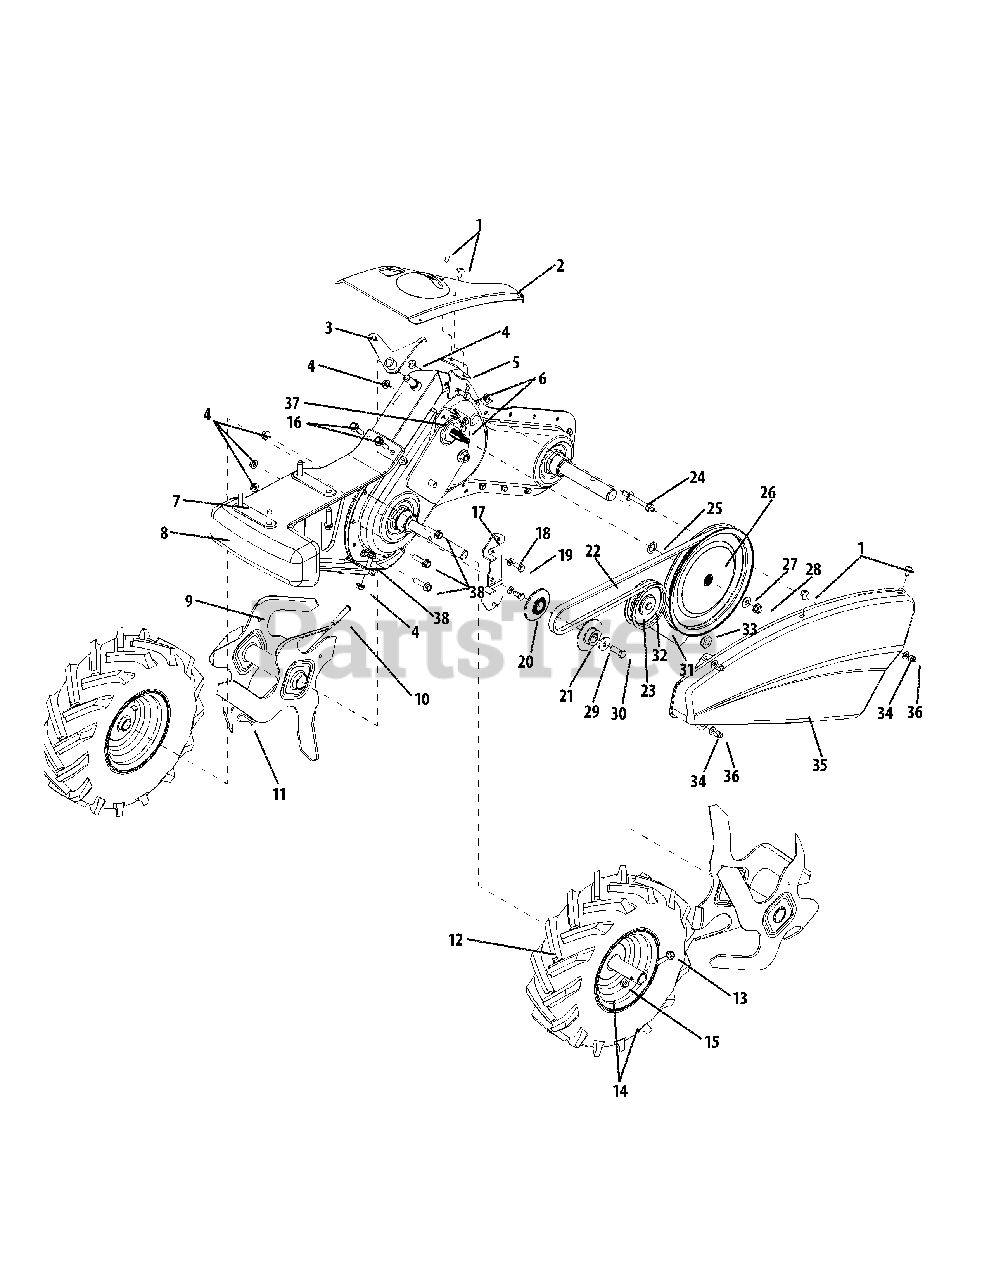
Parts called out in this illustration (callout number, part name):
1	Hex Screw, 1/4-20 x.625
4	Hex Lock Nut,5/16-18
7	Hex Washer Screw, 3/8 -16 x 1.5
8	Frame Counterweight
9	Tine Assembly, Left
9	Tine Assembly, Right
10	Clevis Pin
11	Cotter Pin
12	Complete Wheel Assembly
13	Hex Head Screw, 1/4-20
14	Tire Only, 14"
14	Rim Only, 6.0 x 3.25
15	Flange Lock Nut, 1/4-20
16	Flange Screw, 5/16-18 x 1.25
17	Belt Keeper Bracket Assembly
18	Lock Washer, 5/16
19	Hex Cap Screw, 5/16-24 x.625
20	Inner Pulley Half
21	Outer Pulley Half
22	V-Belt
23	Flat Idler
24	Bolt, 5/16-18 x1/4-28 x 2.35
25	Flat Washer, .635 ID x.930 OD
26	Flat Pulley
27	Spring Washer, .401 ID x.870 OD
28	Flange Lock Nut, 3/8 -24
29	Bell Washer, .396 ID x 1.140 OD
30	Hex Cap Screw, 3/8 -24 x 1.0
31	Idler Bracket
32	Hex Cap Screw, 3/8 -16 x 1.25
33	Shoulder Nut,7/16-20
34	Flat Washer, .271 ID x.630 OD
37	Cable Bracket
38	Oil Drain Extension
39	End Cap
